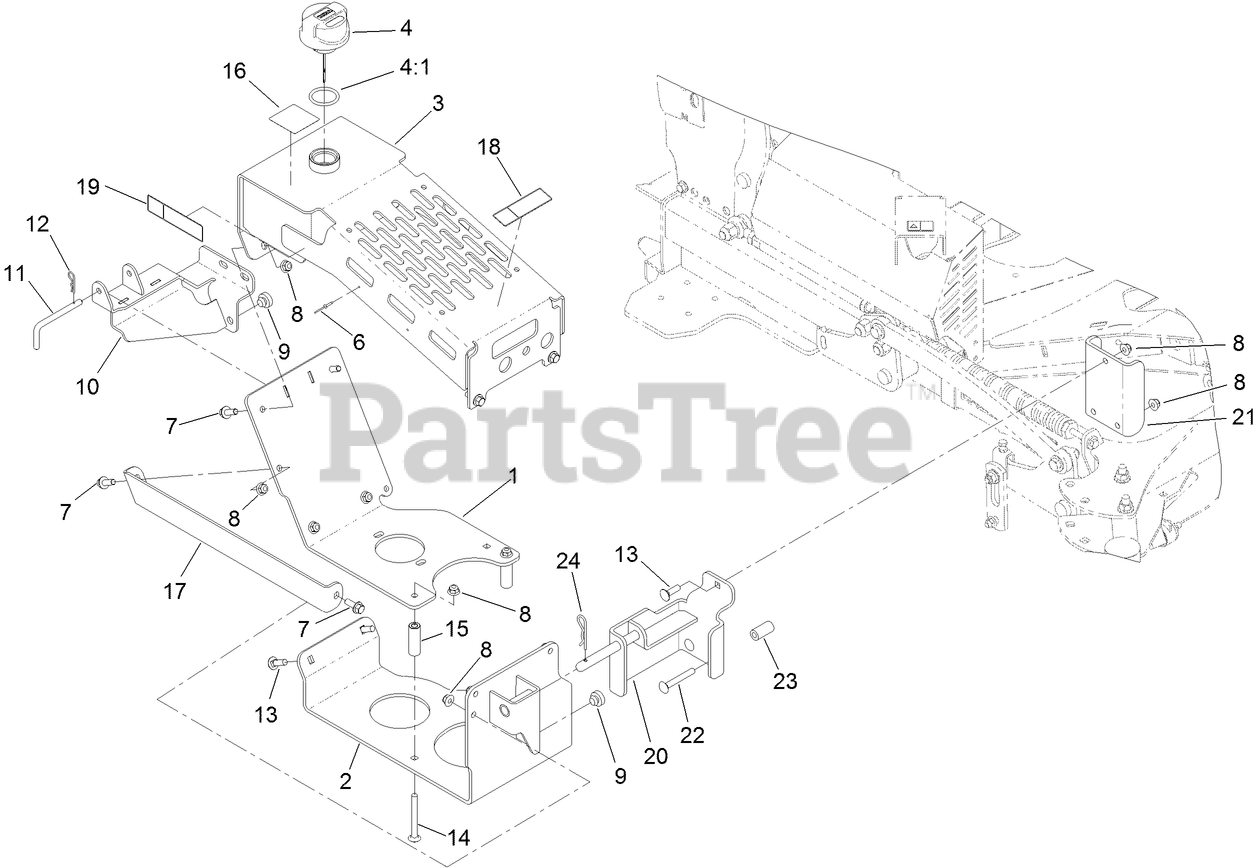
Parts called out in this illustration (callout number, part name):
1	PUMP MOUNT ASM
2	PUMP GUARD BRACKET ASM
3	COOLER COVER ASM
4	CAP-FILLER, BREATHER
4:1	O-RING
6	RIVET-BLIND
7	SCREW-HHF
8	NUT-HF, NI
9	BUMPER-RUBBER
10	MOUNT-FRAME, REAR
11	PIN-LATCH, BRAKE
12	PIN-COTTER
13	BOLT-CARR
14	SCREW-CARR
15	SPACER-HYDRO
16	DECAL-WARNING
18	DECAL-CAUTION
19	DECAL-DANGER
20	MOUNT-FRAME, FRONT
21	BACKPLATE
22	SCREW-CARR
23	SPACER
24	PIN-COTTER
